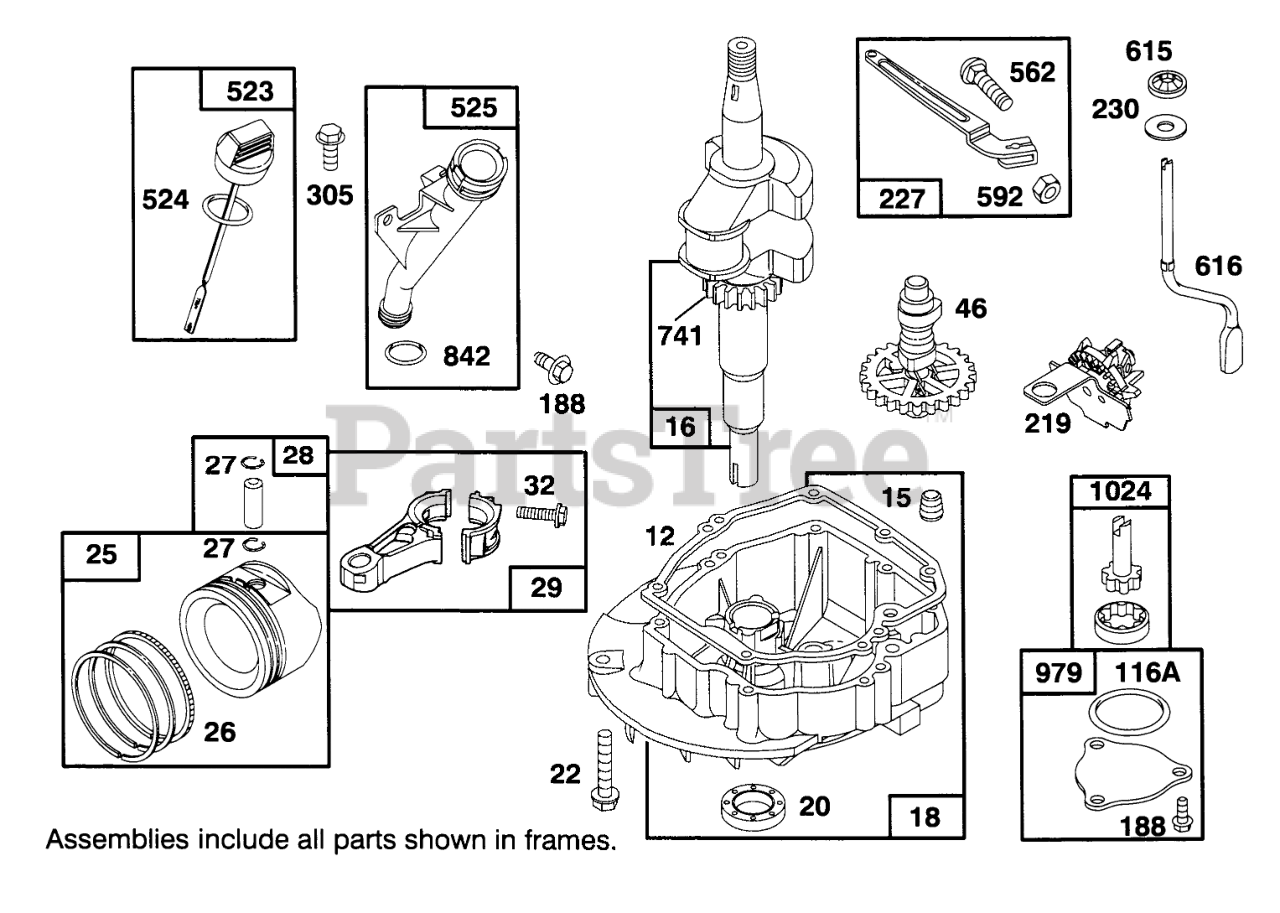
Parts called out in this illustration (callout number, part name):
12	ENGINE BASE GASKET
15	PIPE PLUG
16	Crankshaft
18	ENGINE SUMP
20	SEAL-OIL
22	SCREW - ENGINE BASE
25	STD PISTON ASSEMBLY
26	STD RING SET
27	PISTON PIN LOCK
28	PIN ASM - PISTON
29	CONNECTING ROD
32	SCREW - CONNECTING ROD
46	CAM GEAR
116A	O RING SEAL
188	Screw-Cap
219	GOVERNOR/OIL SLINGER
227	GOVERNOR LEVER ASSEMBLY
230	WASHER
305	SCREW - HEX HEAD
523	DIPSTICK-OIL
524	O-RING
525	OIL FILLER TUBE
562	GOVERNOR LEVER BOLT
592	HEX NUT
615	FASTENER
616	GOVERNOR CRANK
741	TIMING GEAR
842	O-RING
979	OIL PUMP COVER
1024	OIL PUMP
